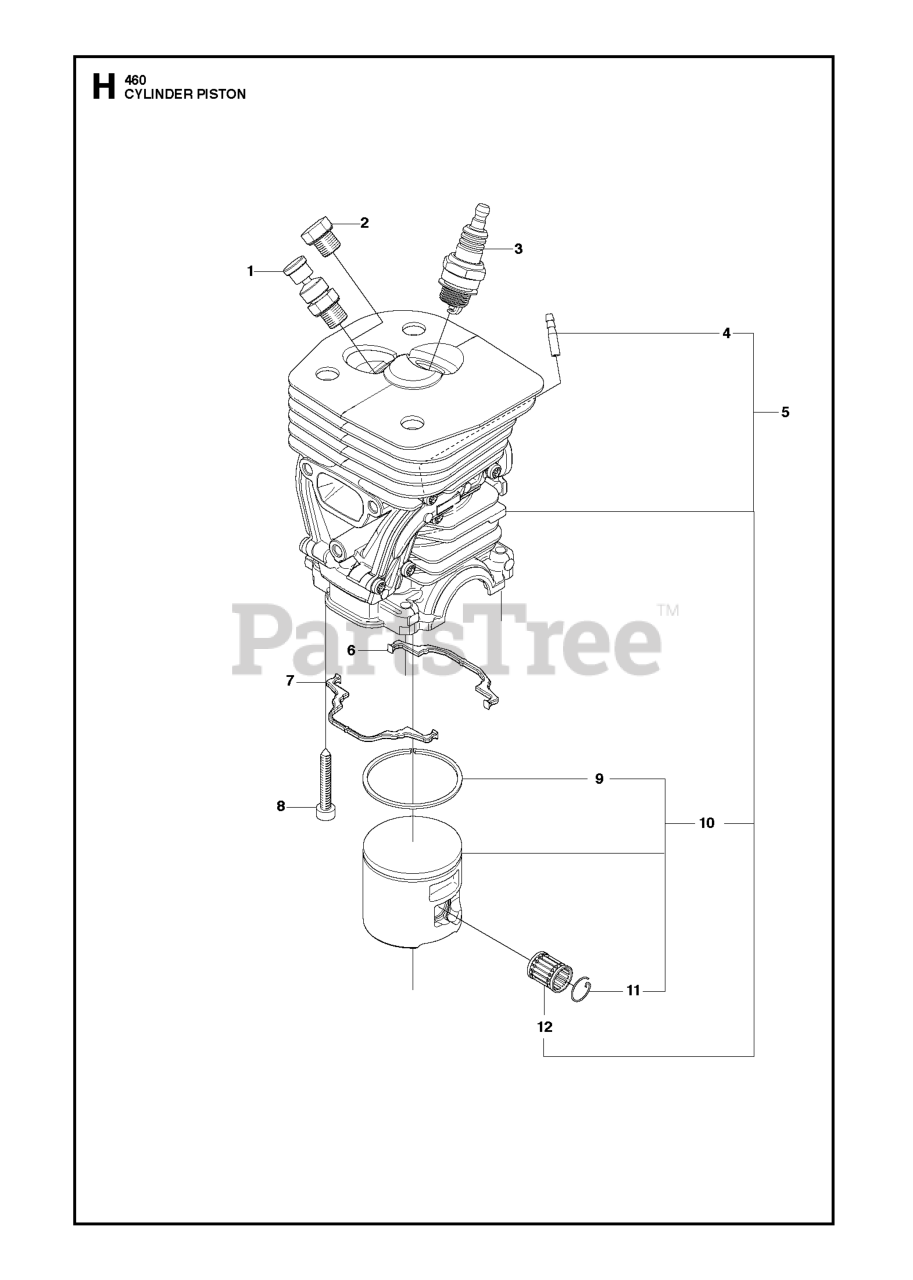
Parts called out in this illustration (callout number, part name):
2	CYLINDER PLUG
3	HQT-1 HH SPARK PLUG - BPMR7A
9	PISTON RING
11	WRIST PIN CLIP
12	SUPPORT BUSHING
